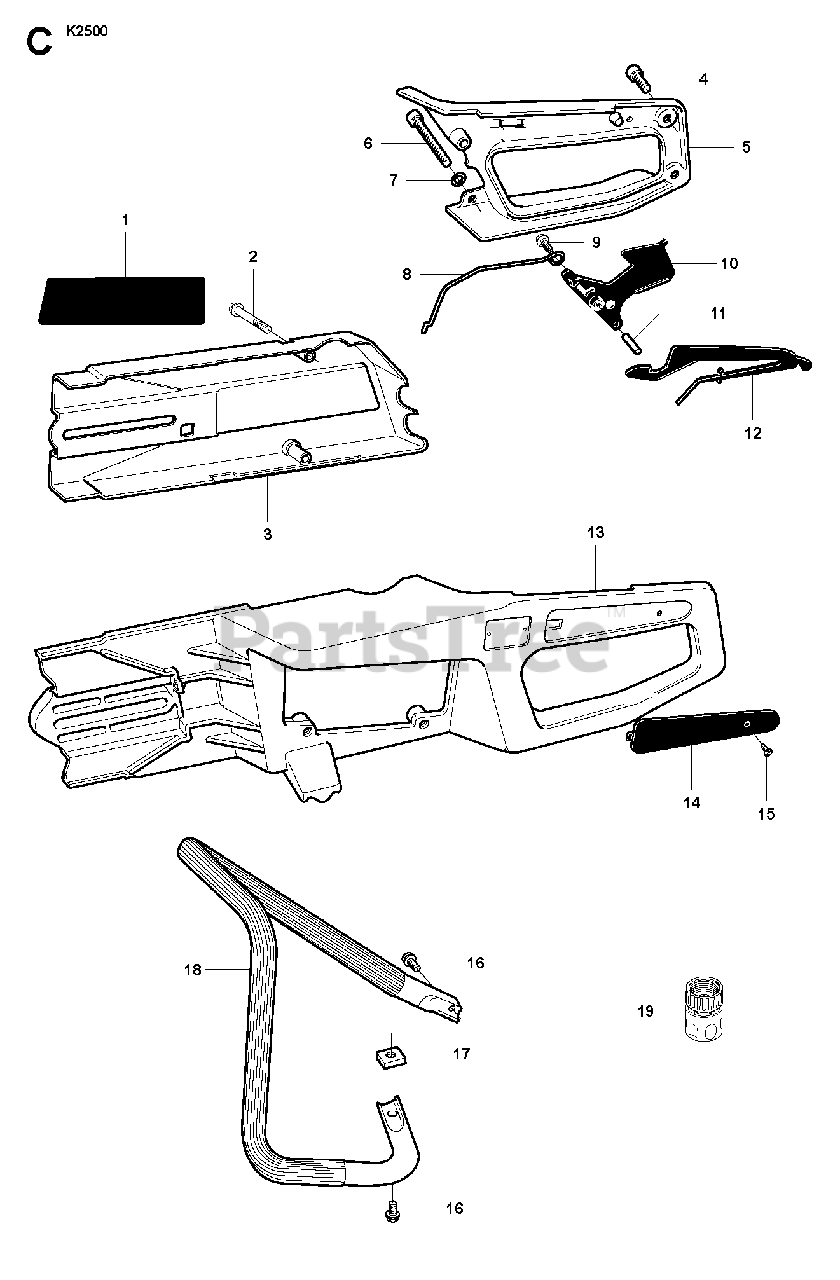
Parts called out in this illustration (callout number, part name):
2	SCREW IHSCFM
9	SCREW CCRPANT
11	PARALLEL PIN
12	THROTTLE LOCKOUT
14	HANDLE INSERT
16	SCREW IHSCFM
19	COUPLER
